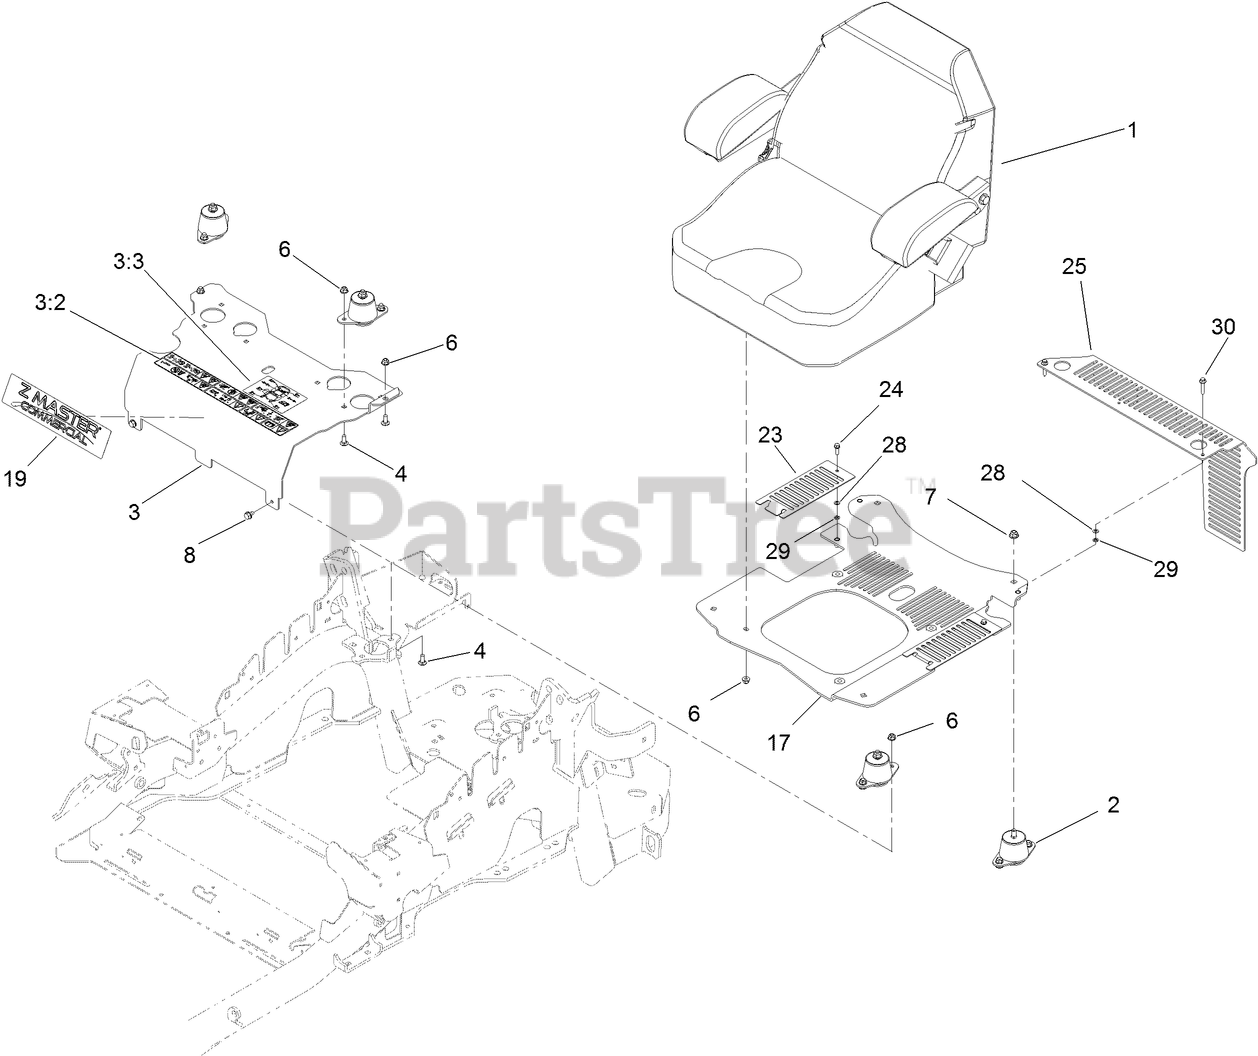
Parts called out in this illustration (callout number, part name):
1	SEAT-STANDARD
2	ISOLATOR-SEAT
3	MOUNT-SEAT
3:2	DECAL-CONSOLE
3:3	DECAL-SERVICE AID
4	SCREW-CARR
6	NUT-HF, NI
7	NUT-HF, NI
8	SCREW
17	SEAT BASE ASM
24	SCREW-HWH
25	GUARD-CE
28	WASHER-FLAT
29	NUT-RETAINER
30	SCREW-HHF
